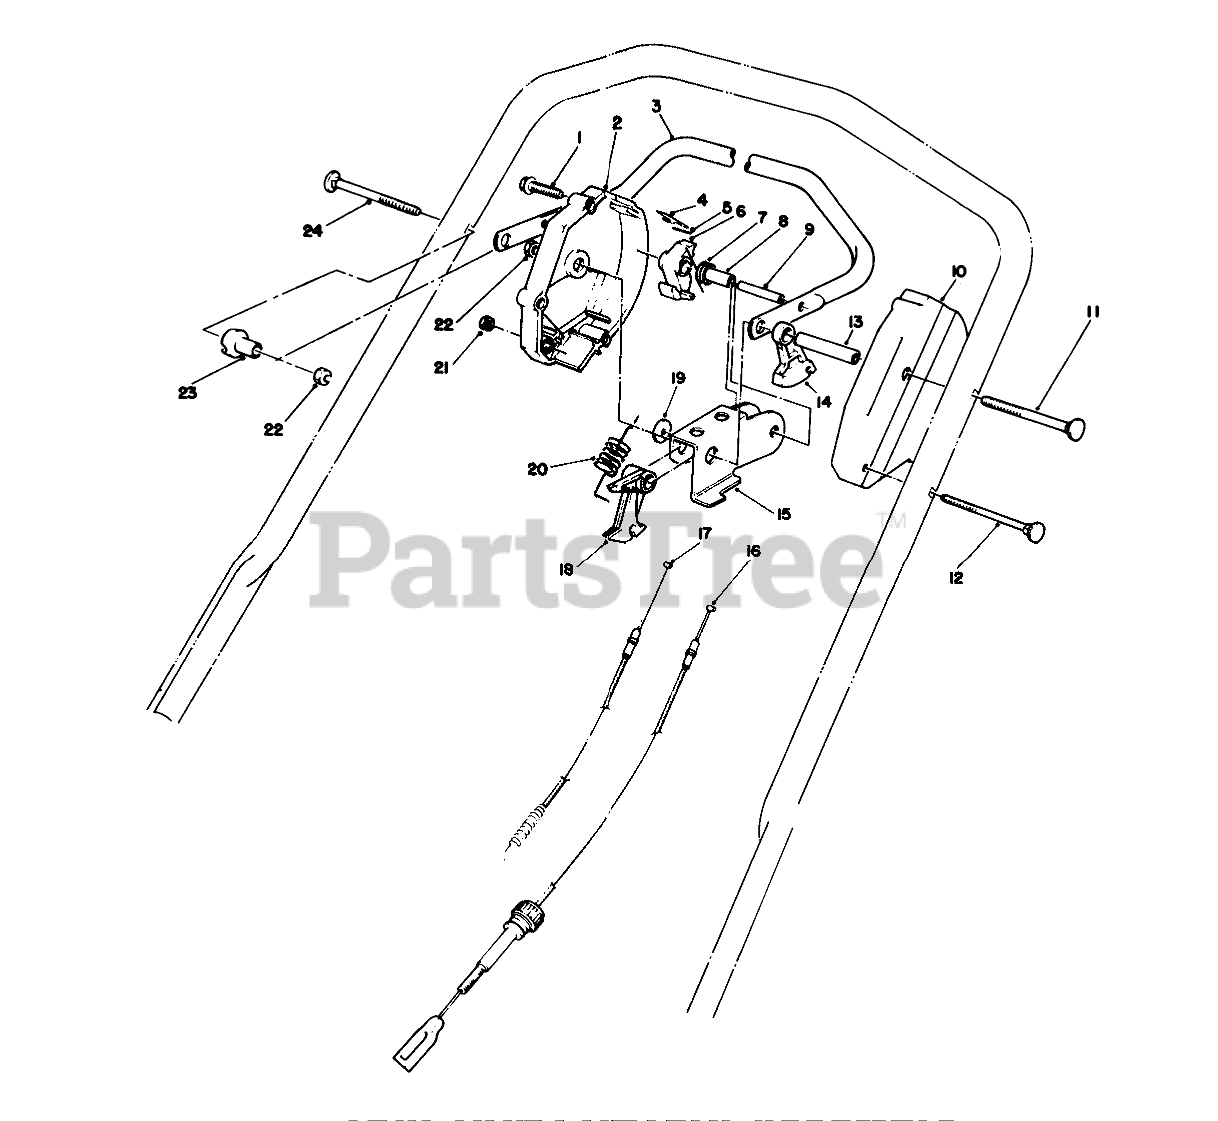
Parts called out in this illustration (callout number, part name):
1	SCREW-HWHTF
2	Housing-Control
3	Bar-Control
4	SPRING-LEAF
5	PIN-INSERT
6	HOOK-CONTROL
7	SPRING-TORSION
8	SPACER
9	PIN-ROLL, SLOTTED
10	HOUSING-CONTROL, LH
11	5/16-18 X 3 HNDLE SCREW
12	HANDLE SCREW
13	TUBING-SPACER
14	LEVER-TRACTION
15	ROCKER
16	TRACTION CABLE
17	Cable-Clutch
18	LEVER-CABLE
19	Washer-Nylon
20	DETENT SPRING
21	NUT-HEX
22	NUT-LOCK, NI
23	SPACER-SUPPORT
24	5/16-18 X 2 HNDLE SCREW
